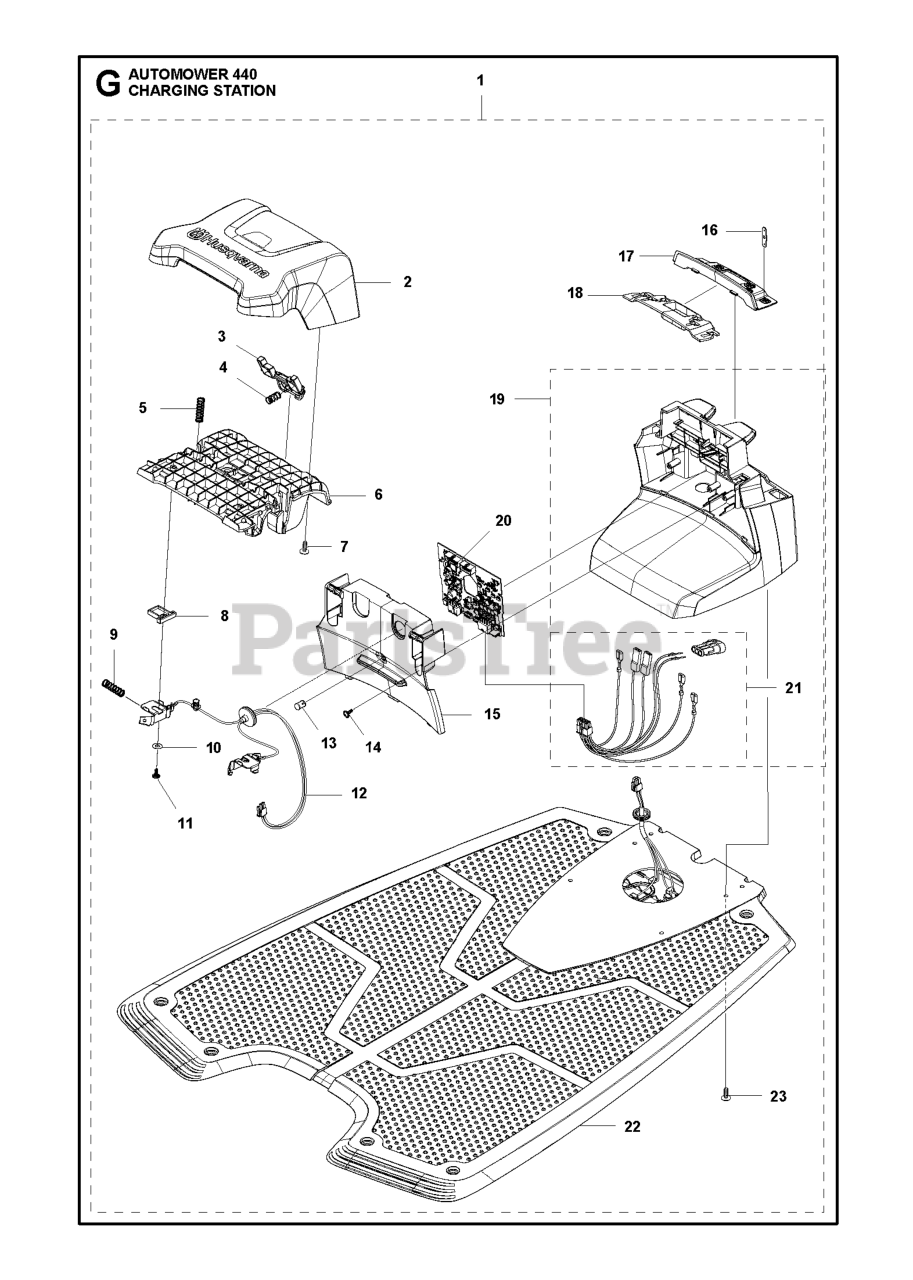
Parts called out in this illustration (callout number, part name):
2	CAP CHARGING STATION
3	BUTTON CHARGING STATION, RELEA
4	SPRING STOP BUTTON
5	SPRING SPRING CAP
6	FRAME CHARGING STATION
7	SCREW 14MM
8	DISTANCE CHARGING STATION
9	SPRING SPRING CAP
10	WASHER
11	SCREW 14MM
12	CABLE ASSY CHARGING CONTACTS
13	LENS
14	SCREW 14MM
15	LID CHARGING STATION 320, ONE
16	TERMINAL TERMINAL CHARGING STA
17	PANEL CHARGING STATION 330, TW
18	HOLDER CHARGING STATION
19	HOUSING ASSY CHARGING STATION
20	PRINTED CIRCUIT ASSY PCBA CS B
21	CABLE KIT GENERATOR BOARD
22	CHARGING PLATE CHARGING PLATE
23	SCREW 14MM
